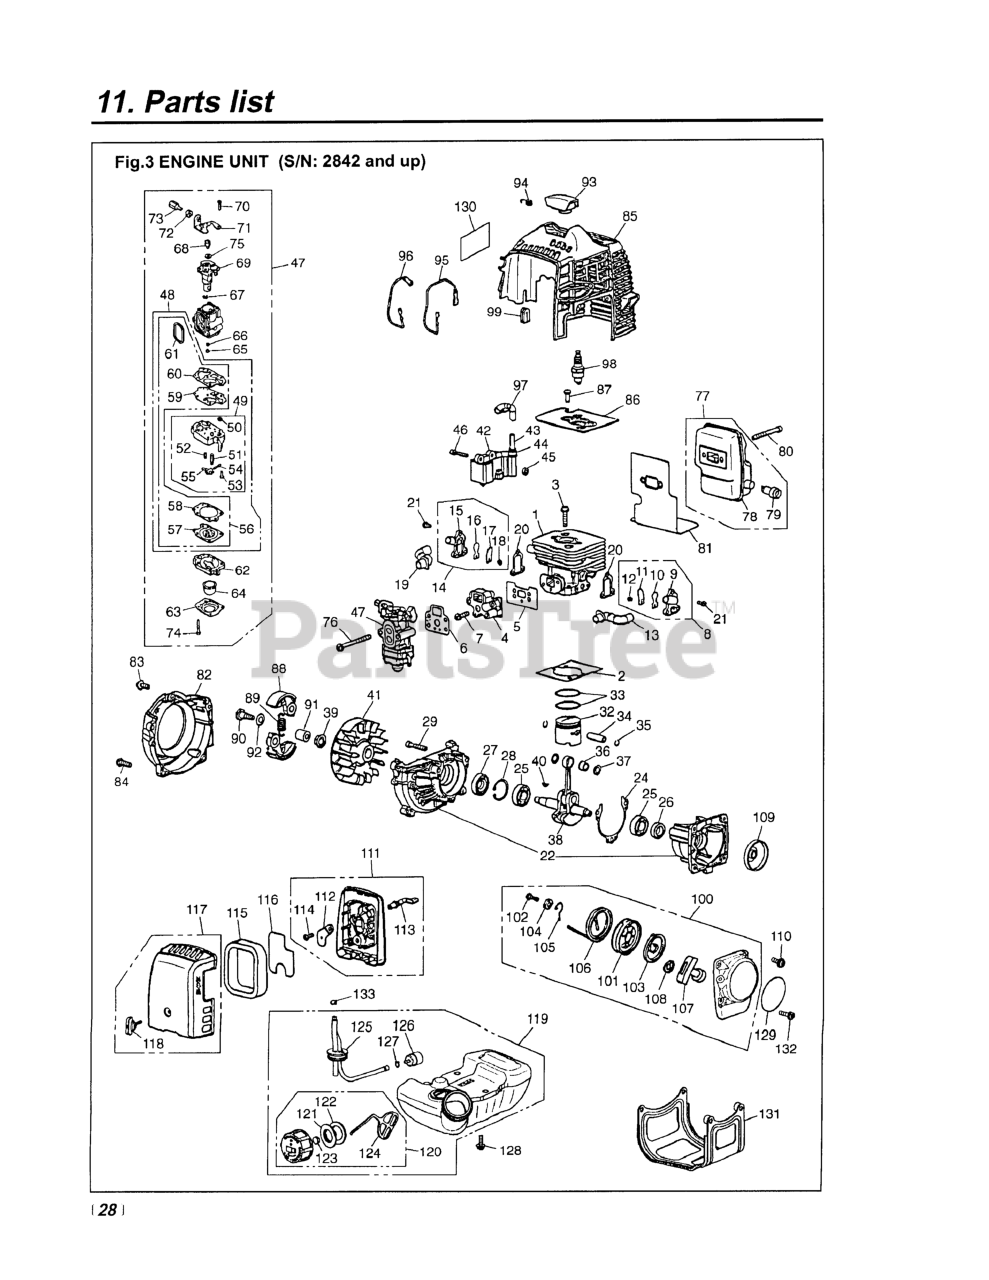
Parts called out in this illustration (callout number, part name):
1	CYLINDER (RPLS -12110)
2	GASKET, BASE
3	BOLT, M5 X 22
4	INSULATOR (RPLS. -13160/13161)
5	GASKET, INSULATOR
6	GASKET, CARBURETOR
7	SCREW, M5X20 (RPLS.1400-75510)
9	CASE VALVE
10	VALVE, REED
11	STOPPER
12	SCREW, M3 x 8
13	PIPE, AIR
16	VALVE, REED
17	STOPPER
18	SCREW, M3 x 8
19	PIPE, AIR (F)
20	GASKET, VALVE
21	SCREW
22	CRANKCASE-C
24	GASKET
25	BEARING
26	SEAL
27	SEAL, OIL (RPLS 1140-21220)
28	RING, SNAP, M28 x 1.2
29	BOLT, M5 X 30
32	PISTON
33	RING, PISTON
34	PIN, PISTON
35	RING, SNAP (RPLS 1101-41320)
36	BEARING (RPLS 1140-41330)
37	WASHER
38	CRANKSHAFT COMPLETE
40	KEY
41	ROTOR
42	COIL-A
43	CORD
44	CAP
45	SPACER (RPLS -71260)
46	BOLT, M4 x 22
49	PUMP BODY ASSEMBLY
50	SCREEN
51	VALVE, INLET
53	SCREW
54	PIN
55	LEVER
57	DIAPHRAGM
58	GASKET, DIAPHRAGM
59	DIAPHRAGM, PUMP
60	GASKET, PUMP
61	RING
62	BODY, PURGE
63	COVER, PUMP
64	PUMP, PRIMING
65	JET (REPLACES 4810-81250)
66	RING, O
67	RING
68	SWIVEL
69	VALVE ASSY
70	SCREW
72	NUT, CABLE ADJUSTER
73	SCREW, CABLE ADJUSTER
74	SCREW
75	WASHER
76	SCREW, M5 x 60
77	MUFFLER ASSEMBLY
78	MUFFLER (REPLACES -15110)
79	ARRESTER
80	BOLT, M5 x 50
82	COVER, FAN
83	SCREW
84	SCREW, M5X20 (RPLS.1400-75510)
85	COVER, ENGINE (RPLS -32110)
86	PLATE
87	SCREW, M5 X 10
88	SHOE
89	SPRING
90	SCREW
91	WASHER
92	WASHER (RPLS -51241)
94	SPRING
95	CORD (BLACK)
96	CORD, EARTH (RED)
99	GROMMET
100	RECOIL ASSEMBLY
101	REEL
102	SCREW
103	SPRING, SPIRAL
104	COLLAR
105	ARM
106	ROPE (REPLACES 4500-75160)
107	KNOB (RPLS -75420)
108	PLATE, STOPPER
109	PULLEY
110	SCREW
111	BODY ASSEMBLY
112	PLATE, CHOKE
113	LEVER, CHOKE
114	SCREW (REPLACES 50030272)
115	ELEMENT
116	SCREEN
117	COVER ASSEMBLY
118	KNOB (RPLS -82220)
120	CAP ASSY (RPLS -85201)
121	HOLDER (REPLACES -85230)
122	PACKING
123	FILTER
124	STOPPER
125	PIPE COMPLETE
126	FILTER (RPLS 1850-85300)
127	CLIP (REPLACES 2841-31280)
128	SCREW
129	LABEL, RECOIL
130	LABEL, COVER (RPLS -31130)
131	GUARD (RPLS 4810-31911)
132	SCREW, M5 x 25
133	CLIP
